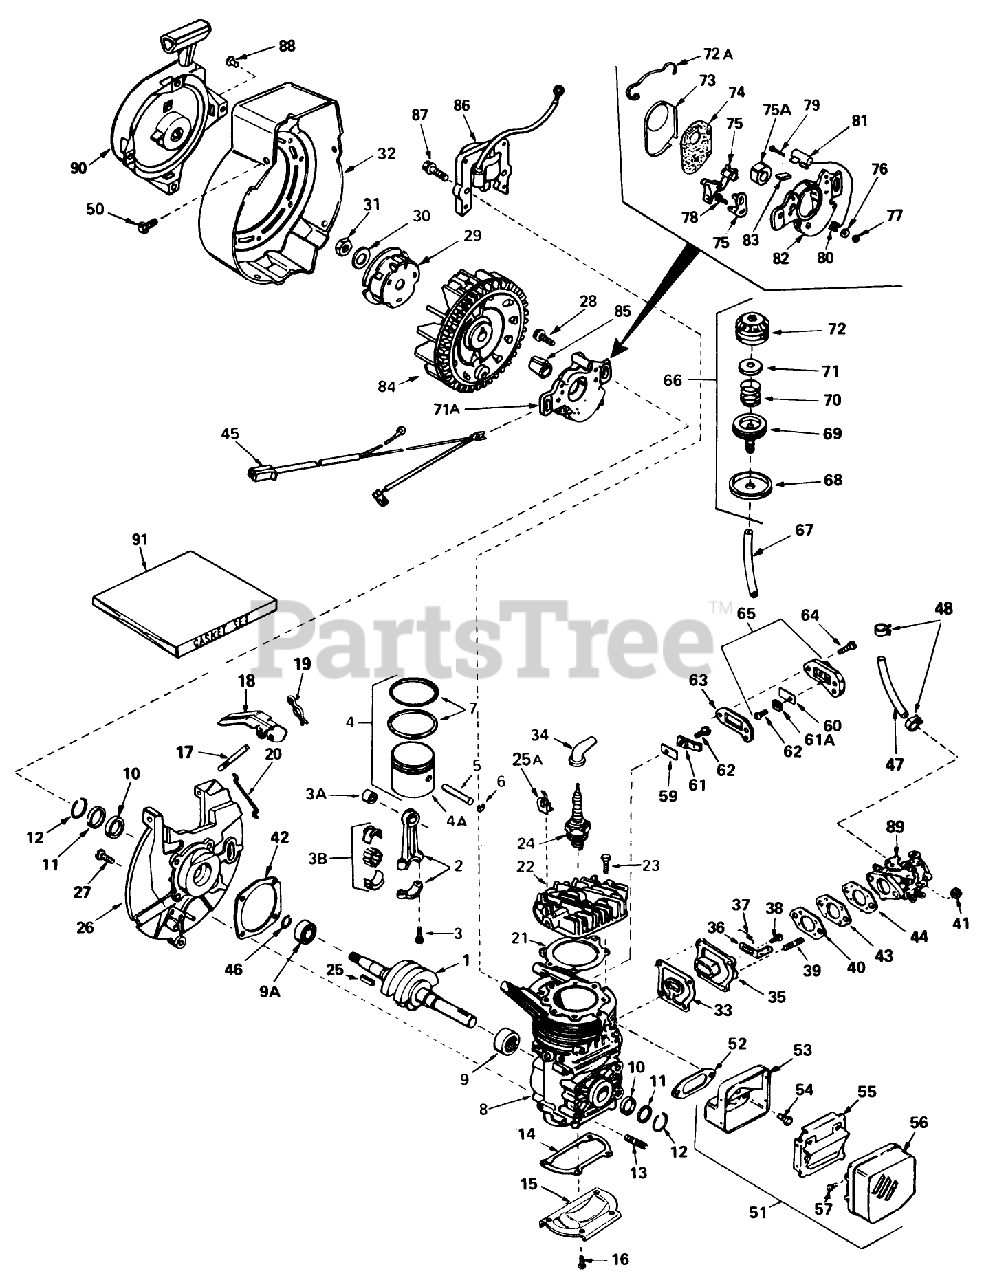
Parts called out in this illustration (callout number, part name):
1	Crankshaft
2	Rod Assembly, Connecting (Incl. #3, 3A 3B)
3	Bolt-Rod, Connecting
3A	Bearing-Cartridge
3B	Bearing Liner Set Needle
4	Piston Assembly (Incl. Ref. #4A thru 7)
4A	Piston
5	Pin, Piston
6	Ring-Retaning
7	Ring Set
8	Block Assembly, Cylinder (Order short block if replacement is required)
9	Bearing-Cartridge
9A	Bearing-Ball
10	Seal, Crankshaft
10	Seal-Oil
11	Retainer, Crankshaft Seal
12	Spring, Crankshaft Seal Retainer
14	Gasket, Cover
15	Plate, Cover
16	Screw (T-25, 10-24 x 1/2)
17	Shaft, Air Vane
18	Vane Assy., Air
19	Clip,Air Vane
20	Link, Governor
21	Gasket, Head
22	Head-Cylinder
23	Screw (T-30, 1/4-20 x 3/4)
24	Head Adjustment Knob
25	Key-Flywheel
26	Base Assy., Housing (Incl. Nos. 29, 30 31)
26	Base Assy., Blower Housing (Incl. Ref. #10 17)
27	Screw
28	Screw, Hex Washer Hd.
29	Starter Cup
29	Cup-Starter
30	Washer-Spring
31	Nut-Flywheel
32	Housing, Blower
32	Housing-Blower
33	Gasket, Port
34	Cover-Spark Plug
35	Adapter, Cover
36	Lever, Adjusting
36	Lever, Adjusting (Used on Type 1601B)
37	Spring, Adjusting Lever
38	Screw
40	Gasket, Carburetor 1/8" thick)
41	Locknut
42	Gasket, Shroud Base
43	Spacer
44	Gasket, Carburetor (1/16"thick)
45	Harness, Wire
46	Ring, Retaining
47	Line-Fuel (8.62)
48	Clamp-Line, Fuel
50	Screw-Hex, Hd.
51	Muffler Assembly (Incl. #53-57)
52	Gasket-Muffler
53	Base-Muffler
54	Screw
55	Baffle, Muffler
56	Cover, Muffler
57	Screw
59	Reed, Compression Release
60	Reed, Compression Release
61	Plate, Reed Hold Down
61A	Plate, Reed Hold Down
62	Screw
63	Gasket, Compression Release
64	Screw
65	Cover Assy., Compression release (Incl. Nos. 60, 61A 62)
66	Primer Assy.
67	Line, Primer
68	Retainer, Primer Bulb
69	Body, Primer
70	Spring, Primer Bulb
71	Washer, Primer Bulb
71A	Stator Plate Assy. (incl. Nos. 107, 111 thru 118 120)
72	Bulb-Primer
72A	Spring Breaker Box
73	Cover-Dust
74	Gasket Dust
75	Breaker Assy.
75A	Cam, Breaker
76	Washer
77	DECAL
78	Breaker Screw
79	Condenser Screw
80	Terminal, Ground
81	Condenser
82	Stator Plate
83	Felt,Cam Wiper
84	FIywheel
84	Magneto
85	SHIELD
86	Lamination Coil Assy. (Incl. No. 42)
87	Screw
87	Screw, Hex Hd. (Used on Type 1601A 1601B)
88	Rivet, Pop (3/16" dia.) (Can be purchased locally)
89	Carburetor (Incl. Ref. #76) (Used on Type 1584A)
89	Carburetor (Incl. No. 76)
89	Carburetor (Incl. Ref. #44) (Used on Type 1601 1601A)
89	Carburetor (Incl. Ref. #44)(Used on Type 1601B)
90	Starter-Rewind
91	Gasket Set (Incl. items marked *)
